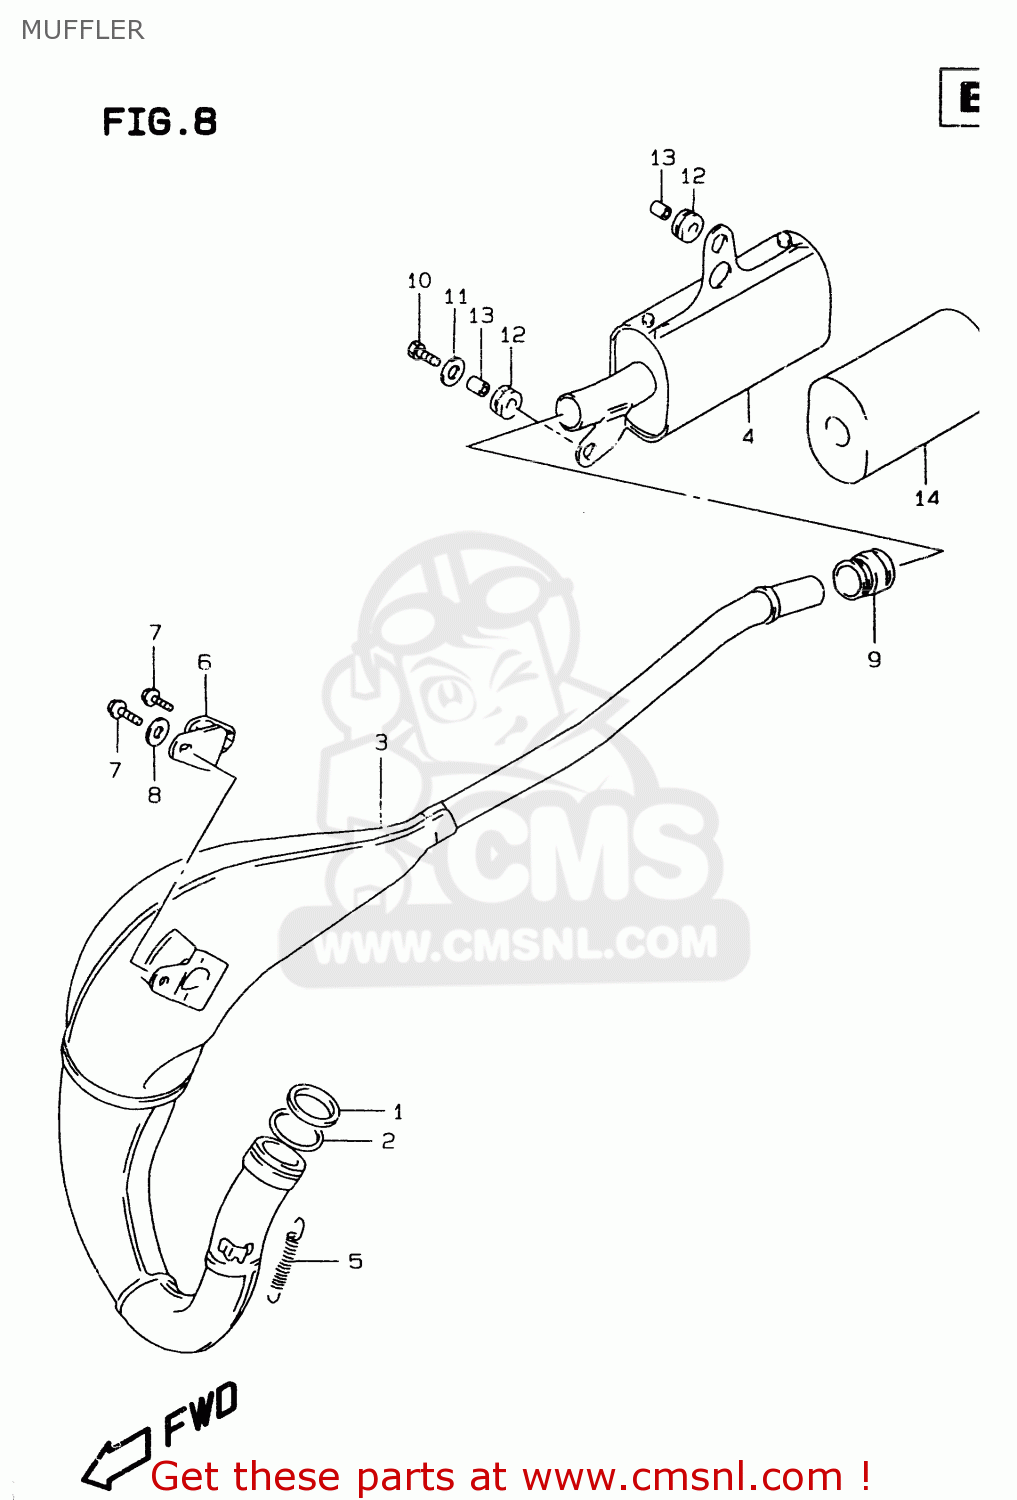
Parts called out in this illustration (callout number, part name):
1	WASHER,EXH FLANGE
2	O RING,EXH FLANGE
3	BODY,MUFFLER 1ST
4	BODY,MUFFLER,SECOND
5	SPRING
6	DAMPER,MUFFLER SUPPORT
7	BOLT
8	WASHER(6.5X16X1.2)
9	CONNECTOR,MUFFLER
10	SCREW
11	WASHER (6.5X20X1.2)
12	CUSHION
13	SPACER
14	SILENCER,MUFFL
